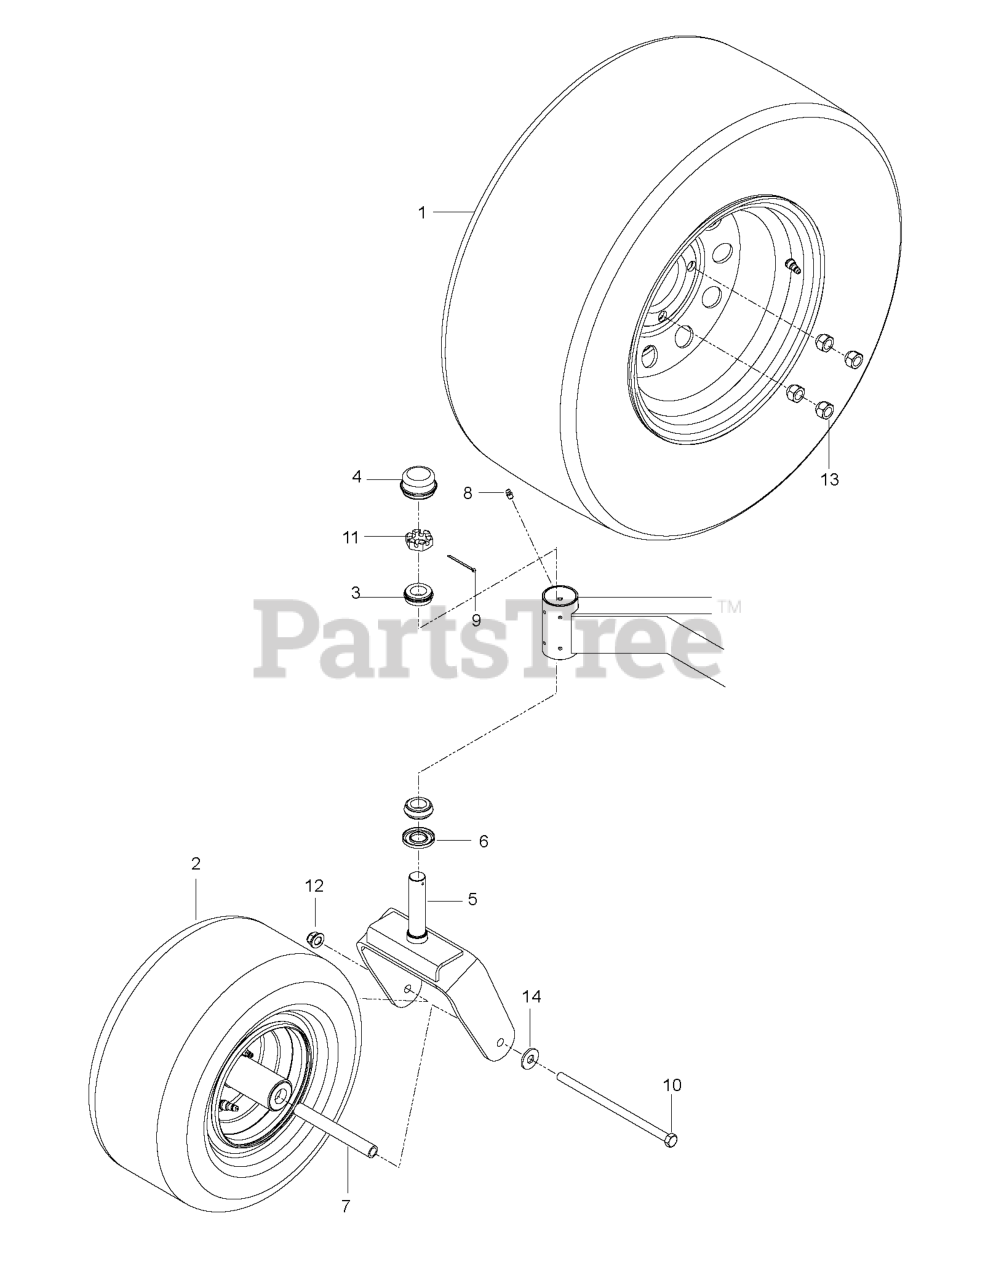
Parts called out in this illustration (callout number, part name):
1	WHEEL.ASSEM.22X10-10.SILVE.ZTR
2	TIRE.ASSEM.CASTER.13X6.5-6.SIL
3	TAPERED ROLLER BRG
4	GREASE CAP
5	FORK.CASTER.ASM.PNT.668
7	SPACER, PIVOT
8	ZERK
9	COTTER PIN 1/8 X 2
10	HEX SCREW 1/2-13 X 9.5 GR5
11	NUT 1"C HEX SLOTTED
12	NUT, 1/2-13 HEX FLG NYLOC ZD
13	LUG NUT 1/2F
14	WASHER.9/16 X 1 3/8 X 12 GA.
